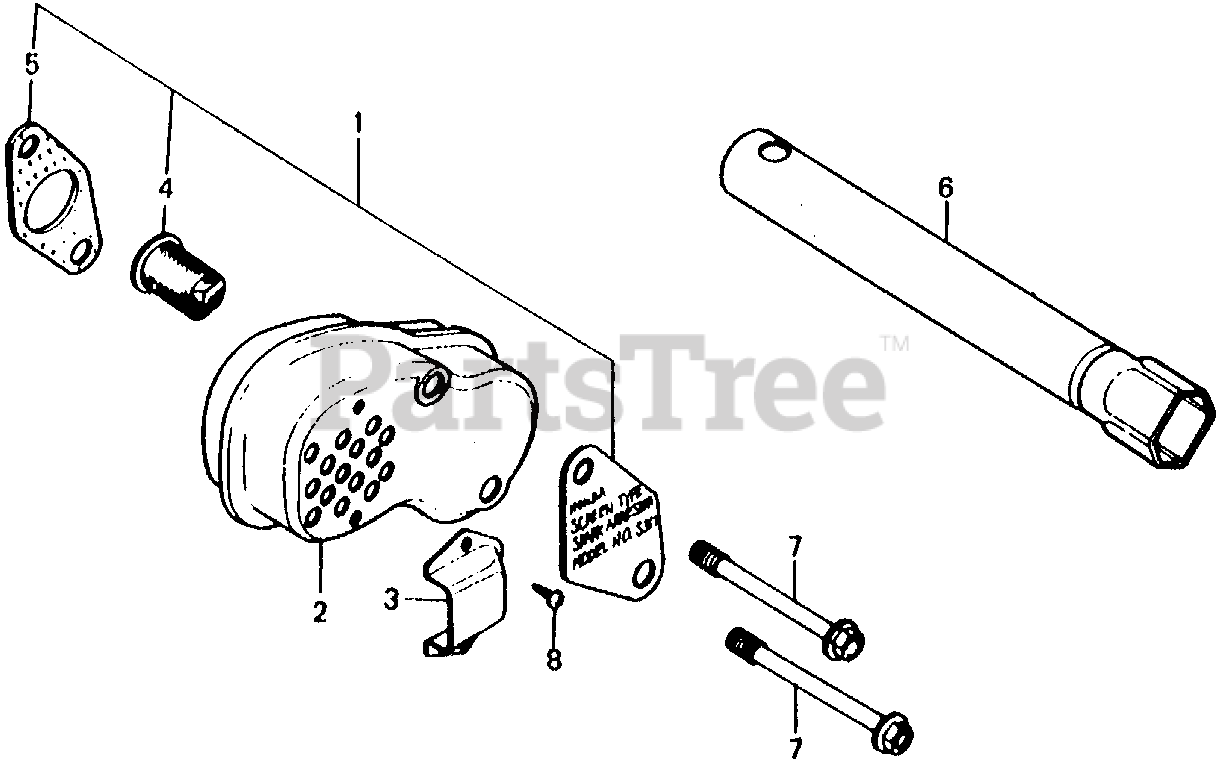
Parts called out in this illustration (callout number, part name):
1	ARRESTER KIT, SPARK
1	ARRESTER KIT, SPARK (NOT AVAILABLE)
2	MUFFLER
3	DEFLECTOR, MUFFLER
4	ARRESTER KIT, SPARK
5	GASKET, MUFFLER (NOT AVAILABLE)
5	GASKET, MUFFLER
6	WRENCH, SPARK PLUG
7	BOLT, FLANGE (8X90)
8	SCREW, TAPPING (4X8)
